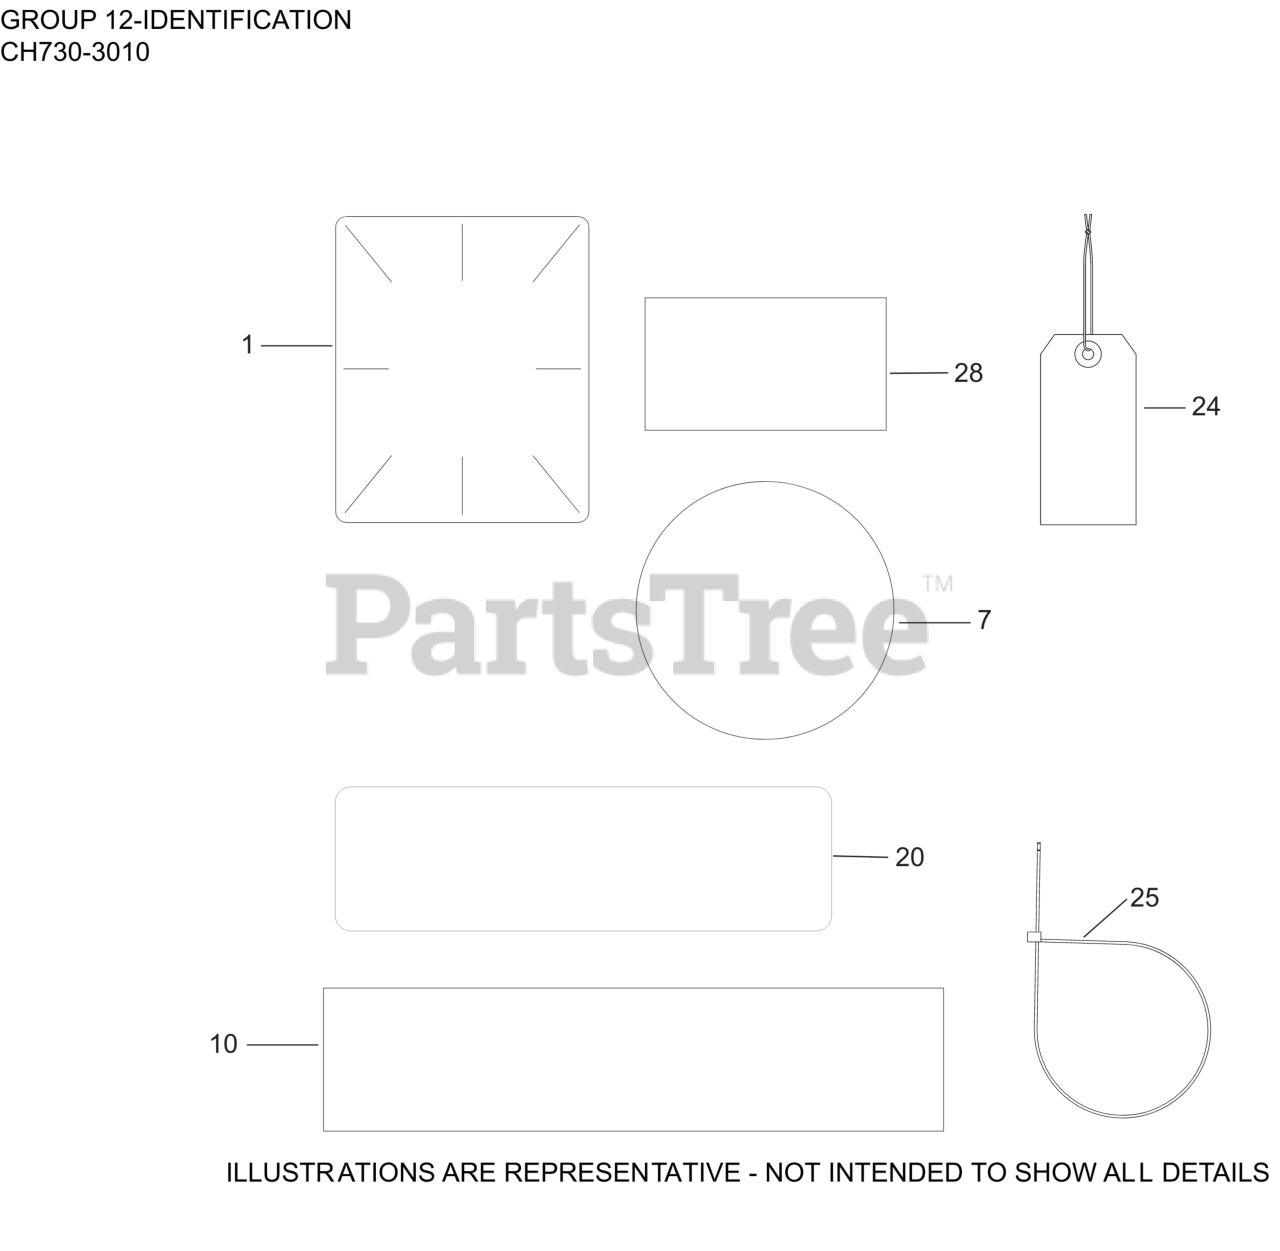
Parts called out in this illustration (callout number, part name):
1	LABEL, CLEAR LAMINATION
7	LABEL, GRASS SCREEN
10	DECAL, STOPPING INSTRUCTION
20	DECAL LPAC, 23.5 HP/725cc/CH730
24	TAG, HANG (OIL SENTRY)
28	DECAL, USA
